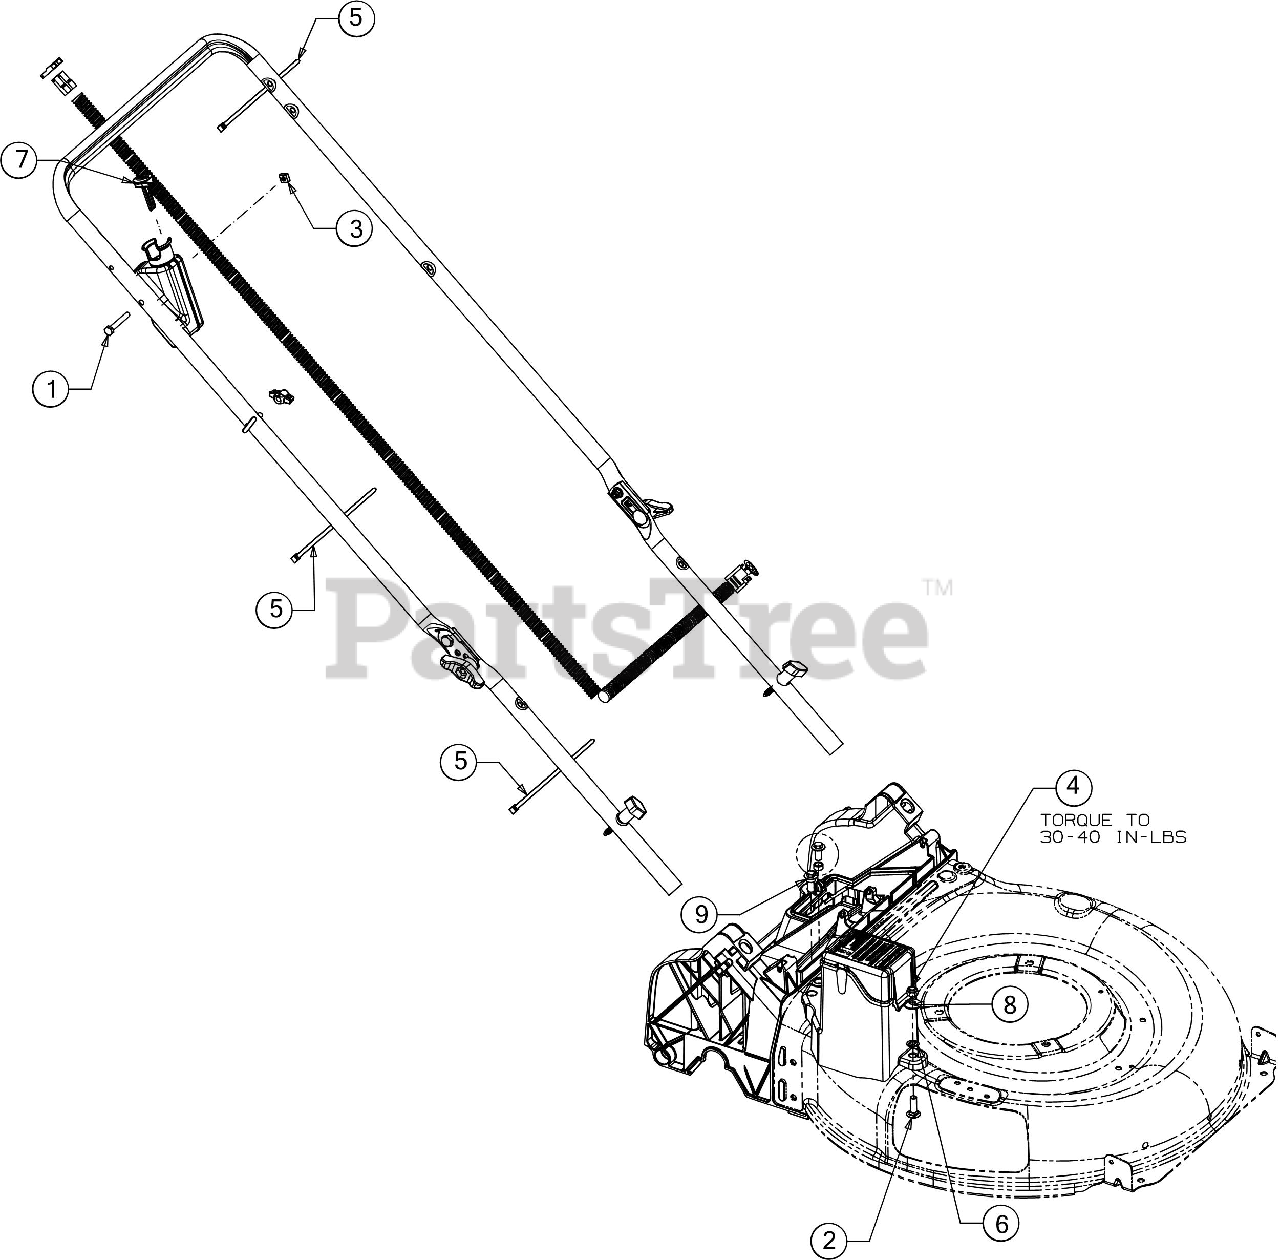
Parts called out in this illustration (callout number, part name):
1	HEX SCREW 1/4-20 X 1.75
2	CARRIAGE BOLT 5/16-18 X 1.00
3	SQUARE NUT 1/4-20
4	HEX NUT
5	CABLE TIE 7"
6	PUSH NUT
7	PUSH KEY
8	BELL WASHER .337 X.867 X .057
9	SHOULDER SCREW 5/16-14 X .972
